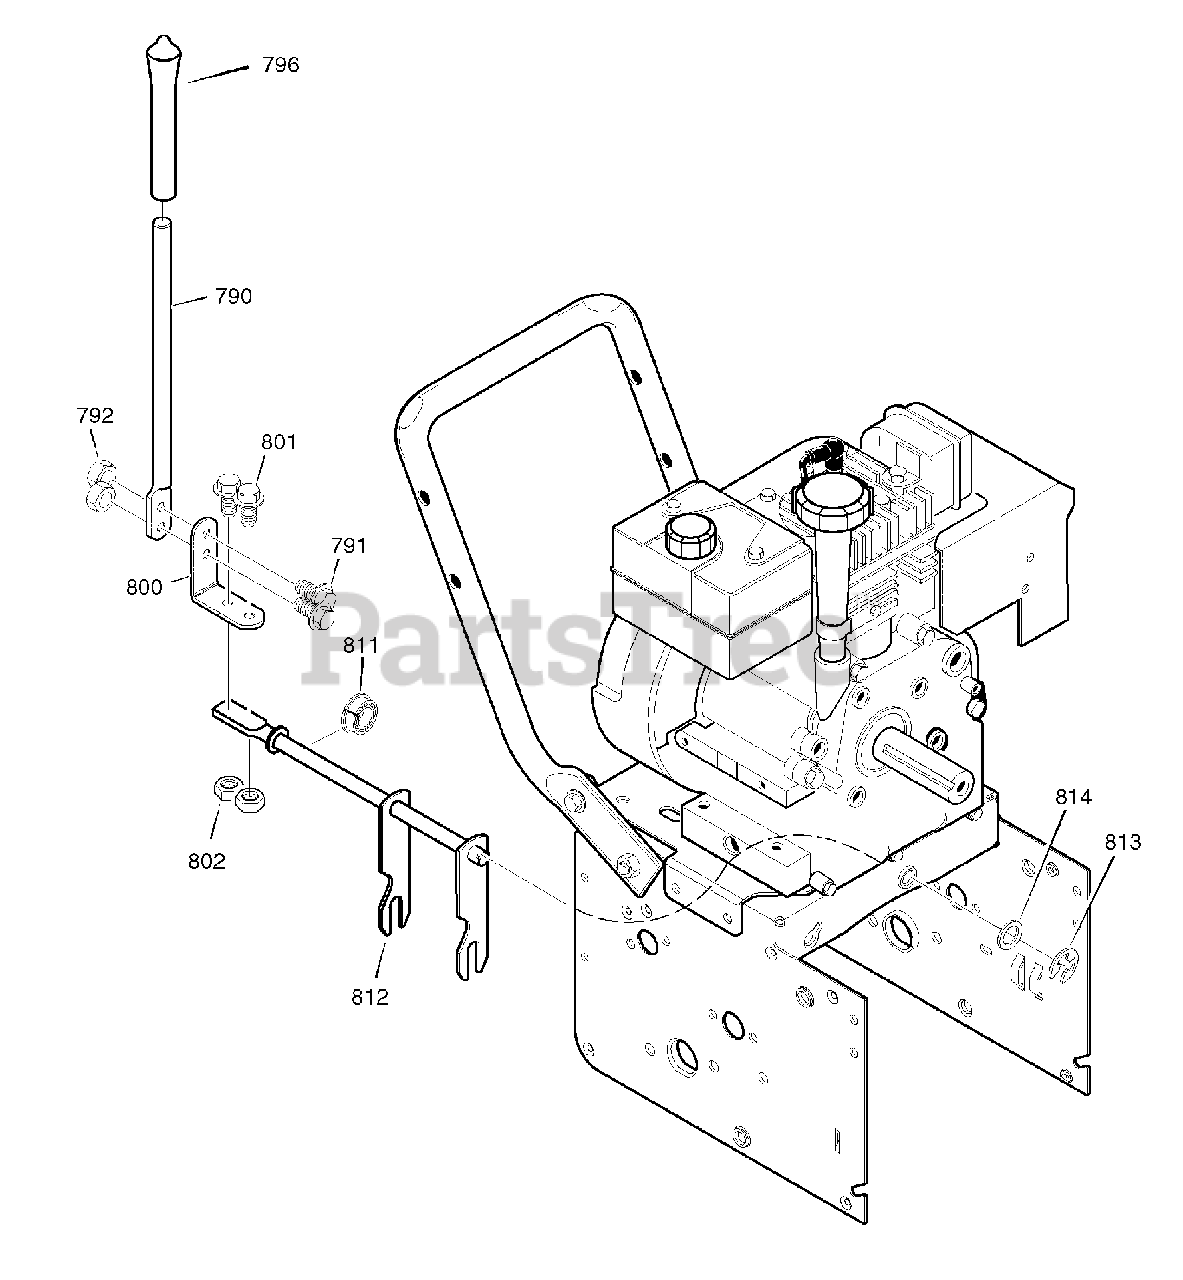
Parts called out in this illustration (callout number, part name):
790	ROD, SHIFT
791	SCREW, 1/4-20X.75
792	NUT, 1/4-20
796	KNOB, SLIP
800	LEVER, SPRING
801	SCREW, 1/4-20X.75
802	NUT, 1/4-20
811	BEARING, FLANGED
812	ROD ASSY., SPEED SELECT
813	RETAINER, RING
814	WASHER
